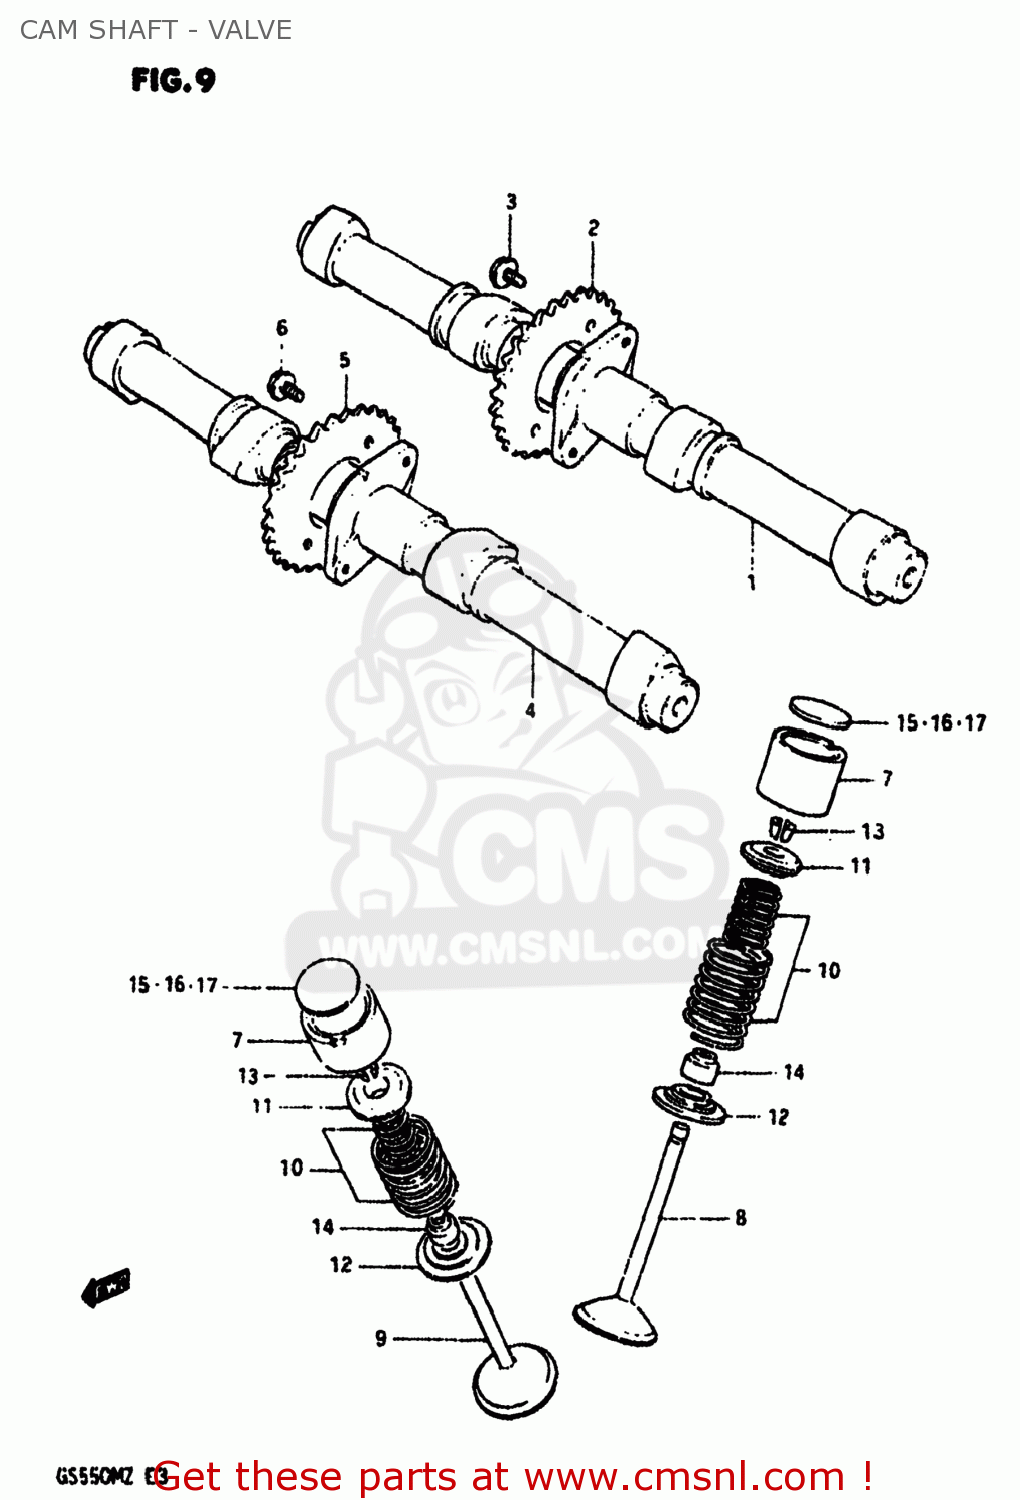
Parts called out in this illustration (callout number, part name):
1	CAMSHAFT,INTAKE
2	SPROCKET,INTAKE CAMSHAFT
3	BOLT(7X11)
4	CAMSHAFT,EXHAUST
5	SPROCKET,EXHAUST CAMSHAFT
6	BOLT(7X11)
7	TAPPET
8	VALVE,INTAKE
9	VALVE,EXHAUST
10	SPRING SET,VALVE
11	RETAINER,VALVE SPRING
12	SEAT,VALVE SPRING
13	COTTER VALVE
14	SEAL,OIL(7X14.4X9)
15	SHIM,TAPPET
16	SHIM,TAPPET
17	SHIM,TAPPET
18	SHIM SET,TAPPET
19	CASE
